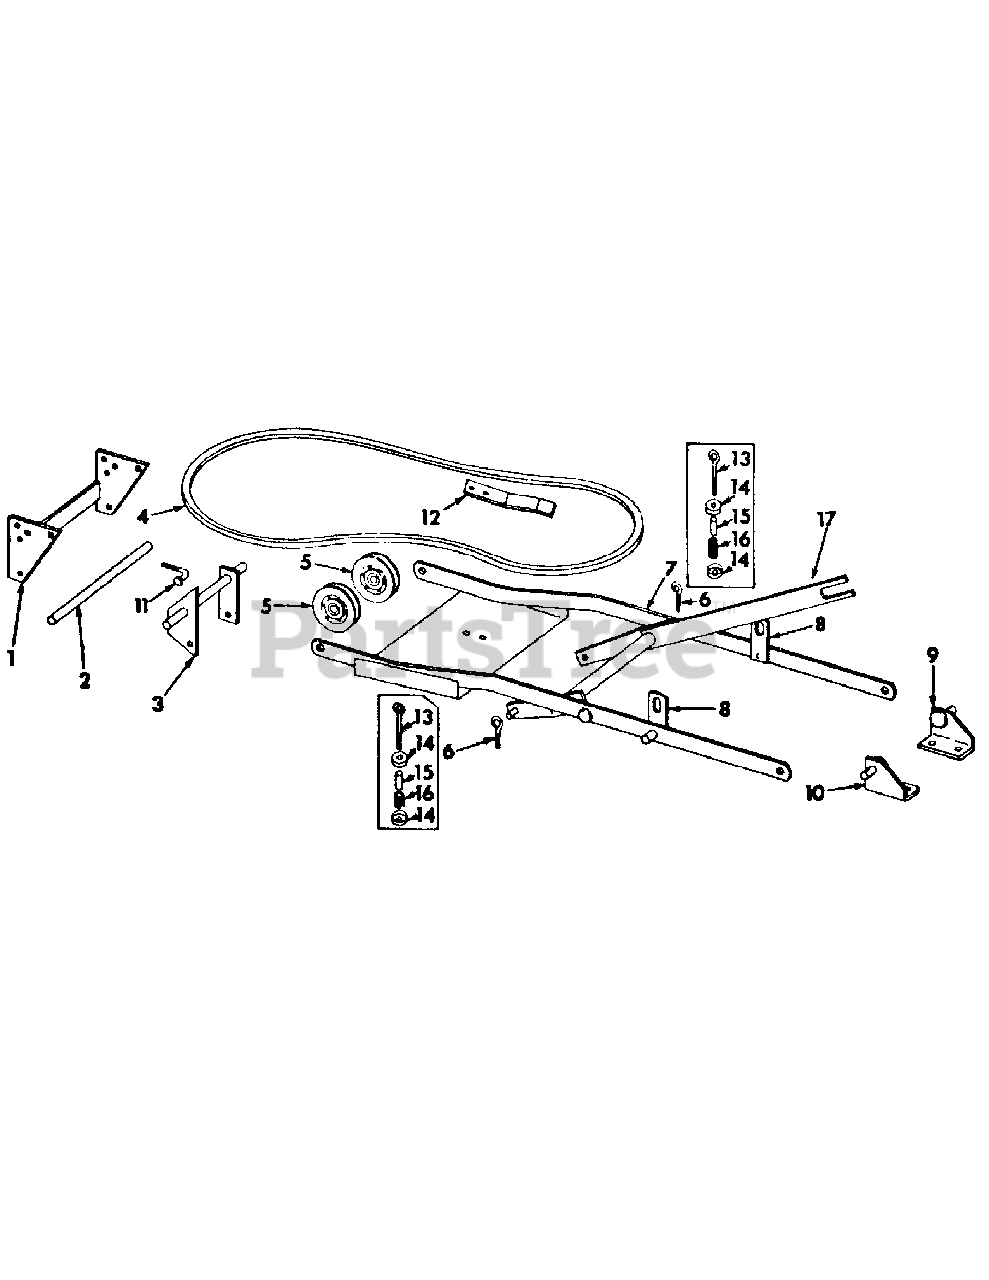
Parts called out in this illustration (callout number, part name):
1	Bracket Assy, Mounting
2	Pin, Front Mounting
3	Support Assy, Idler
5	Pulley, Drive Belt Idler -Replaces IH-473-467-R91
6	Eyebolt, -38 In. & 42 In. Mower
7	Frame Assy, Lift -1963 to 1966-
8	Link Assy, Lift
9	Bracket Assy, Rear Hanger RH
10	Bracket Assy, Rear Hanger LH
12	Brace, Mower Stop Strap -48 In. Mower
13	Bolt, Mower Mounting Eye -48 In. Mower
14	Washer, Spring Retainer -48 In. Mower
15	Spacer, Restraint -48 In. Mower
16	Spring, Mower Mounting -48 In. Mower
17	Support Assy, Front Pivot Link -1967 and Since
